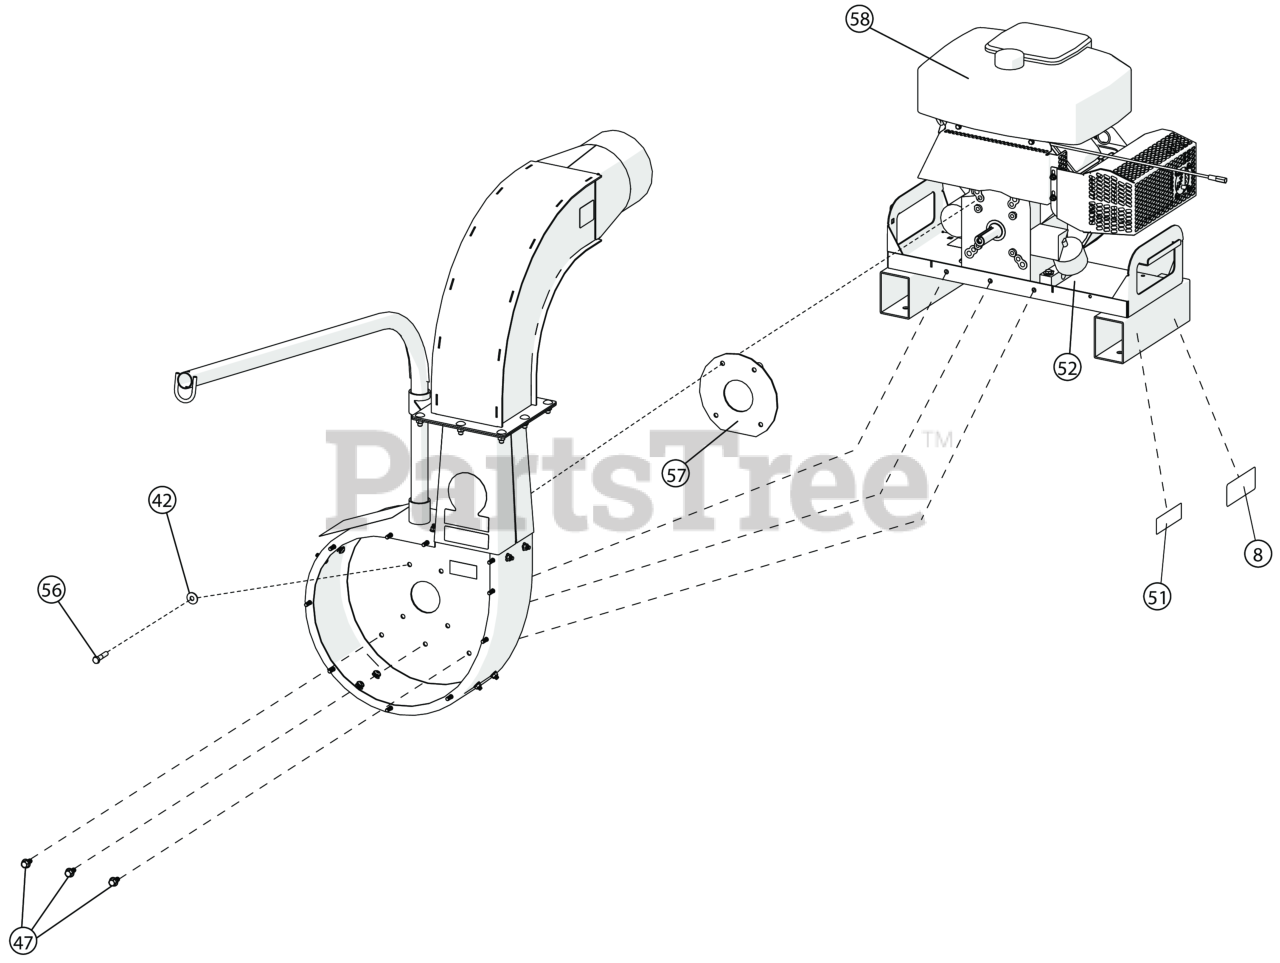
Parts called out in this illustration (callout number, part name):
8	LABEL WARNING ENGINE OVERHEAT
42	WSHR-STL, BLV, .386" X 1.063" X .082" MZ
47	SER HEX WASHER 3/8" - 16
51	LABEL SPARK ARRESTOR
52	BASE ENGINE WA
56	SCREWCAP 3/8"-16X3" HCS ZP
57	SPACER ENGINE WA DL12/13
58	ENGINE SUBARU ELECTRIC
